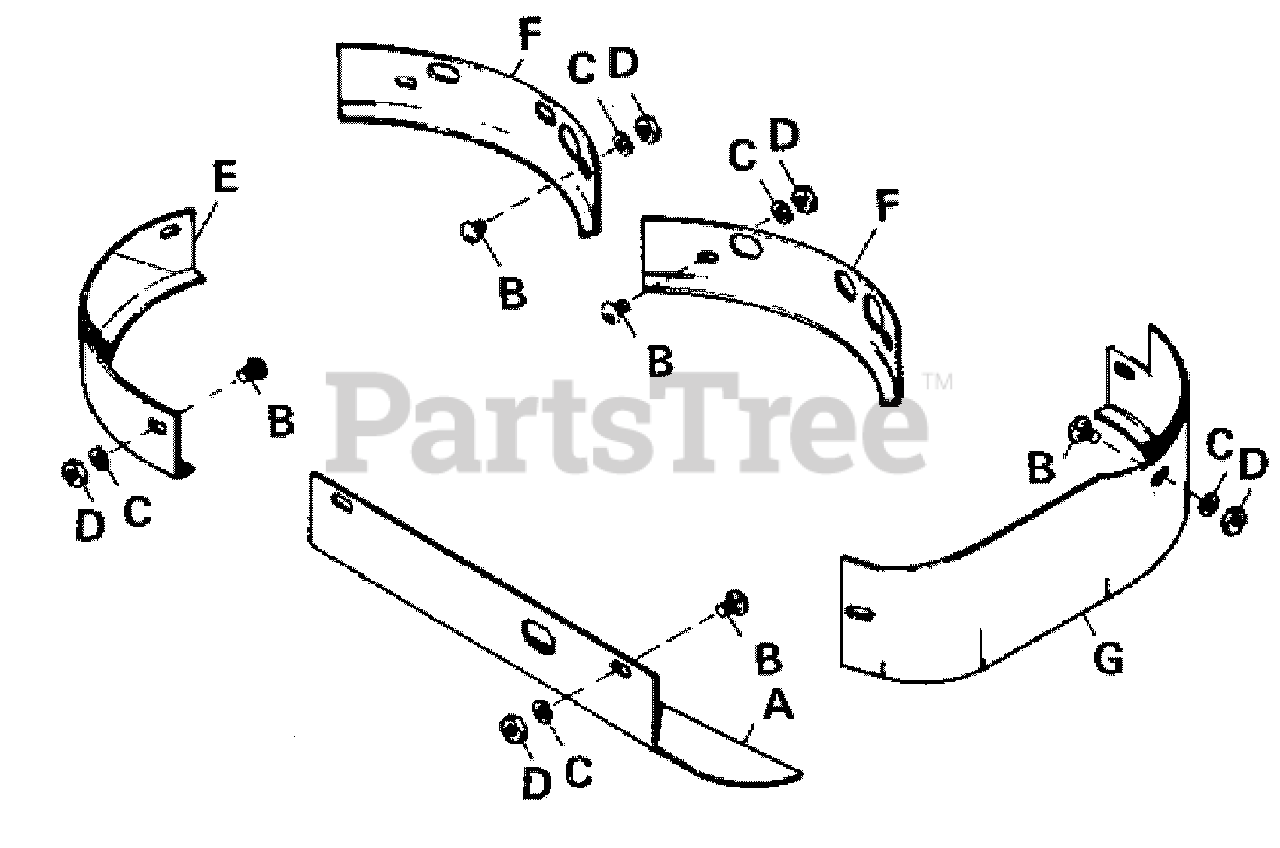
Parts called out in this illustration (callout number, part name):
A	CENTER FRONT MULCHER BAFFLE
B	BOLT, Carriage, 5/16-18 x 1/2"
C	WASHER, Lock, 5/16"
D	NUT, Hex, Full, 5/16-18"
E	FRONT RIGHT HAND MULCHER BAFFLE
F	CENTER REAR MULCHER BAFFLE
G	LEFT HAND MULCHER BAFFLE
